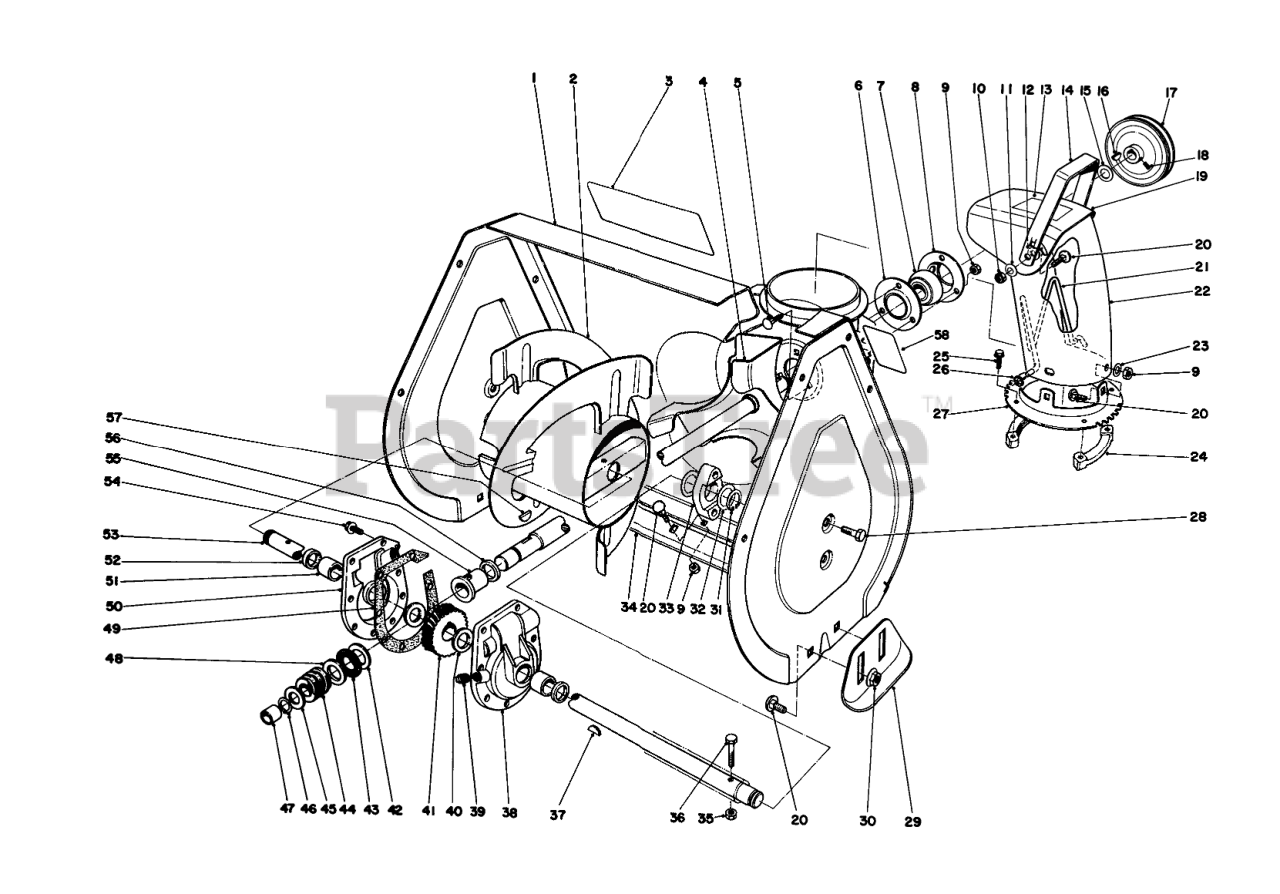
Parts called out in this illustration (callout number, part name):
1	Auger Housing
2	Auger R.H.
3	AUGER WARNING DECAL
4	Shaft & Impeiler
5	BOLT-CARR
6	FLANGE-CUP, BEARING
7	Ball Bearing
8	FLANGE-CUP, BEARING
9	NUT-LOCK, NI
10	NUT-LOCK, CONE
11	WASHER-BELLEVILLE
12	WASHER-RUBBER
13	Decal-Danger
14	Handle Deflector
15	WASHER
16	KEY-WOODRUFF
17	PULLEY
18	SCREW-SET, SQH
19	Deflector (Inc. Ref. #13)
20	BOLT-CARR
21	CHUTE WIRE
22	DISCHARGE CHUTE
23	WASHER-PLAIN
24	RING-CHUTE, RETAINER
25	SCREW-SPECIAL
26	NUT-PUSH
27	Chute Ring
28	SCREW-HWHTF
29	Skid
30	NUT-HF
31	RING-RETAINING
32	WASHER
33	BEARING-AUGER
34	Blade-Scraper
35	NUT-LOCK, CONE
36	SCREW-HH
37	KEY-WOODRUFF
38	Gear Case L.H. (Incl. Ref. #51 & 52)
39	PLUG-PIPE, SQH
40	WASHER-THRUST
41	Gear
42	WASHER-THRUST
43	BEARING-THRUST
45	WASHER-THRUST
46	Ring-Snap
47	BUSHING
48	WASHER-THRUST
49	GASKET-CASE, GEAR
50	Gear Case R.H. (Incl. Ref. #51 & 52)
51	BUSHING
52	Oil Seal
53	AUGER SHAFT
54	SCREW-TAPTITE
55	BUSHING-INPUT
56	RING-QUAD
57	KEY-WOODRUFF
58	DECAL-WARNING, AUGER
